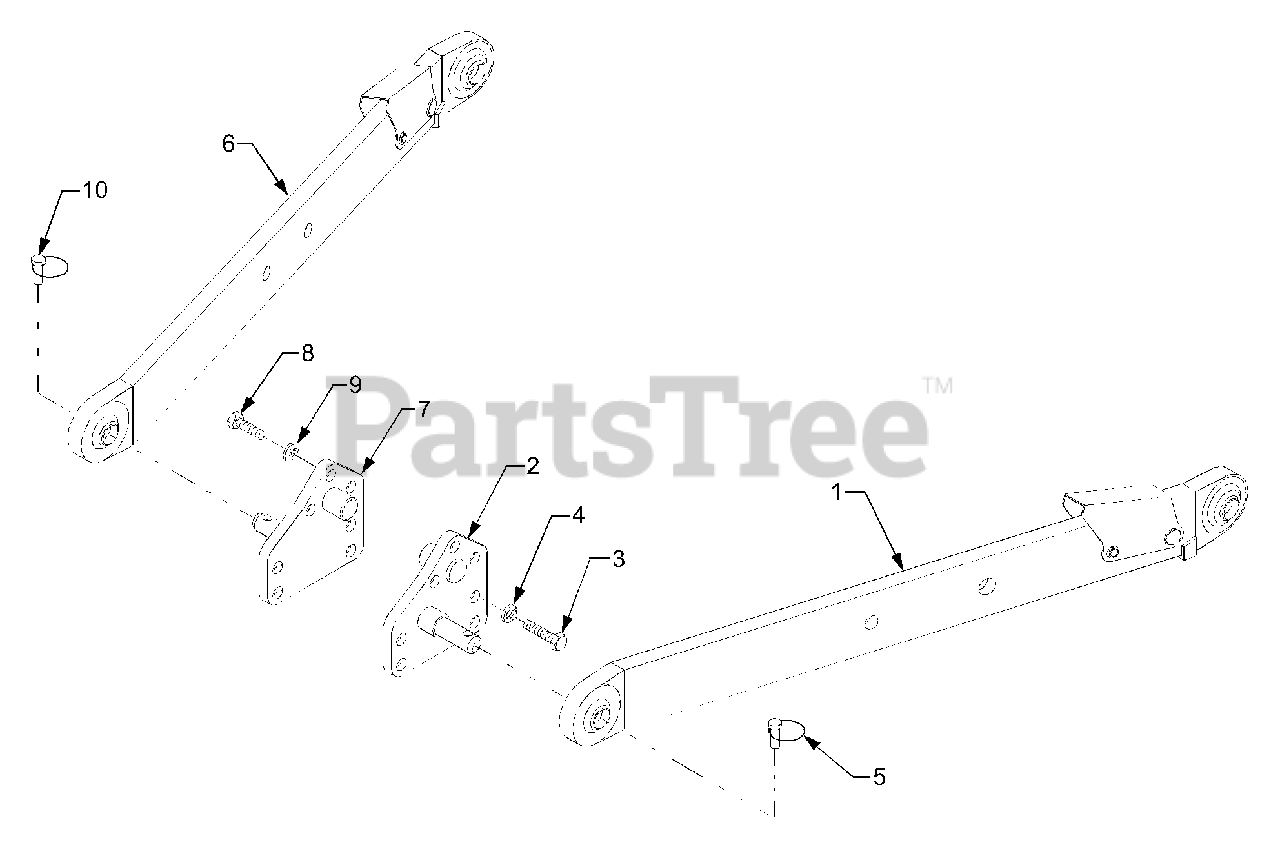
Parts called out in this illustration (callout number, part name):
1	Lower Like Ass'y(LH)
2	Pin, Lower Link
4	Washer, Spring
6	Lower Like Ass'y(RH)
7	Pin, Lower Link
9	Washer, Spring
